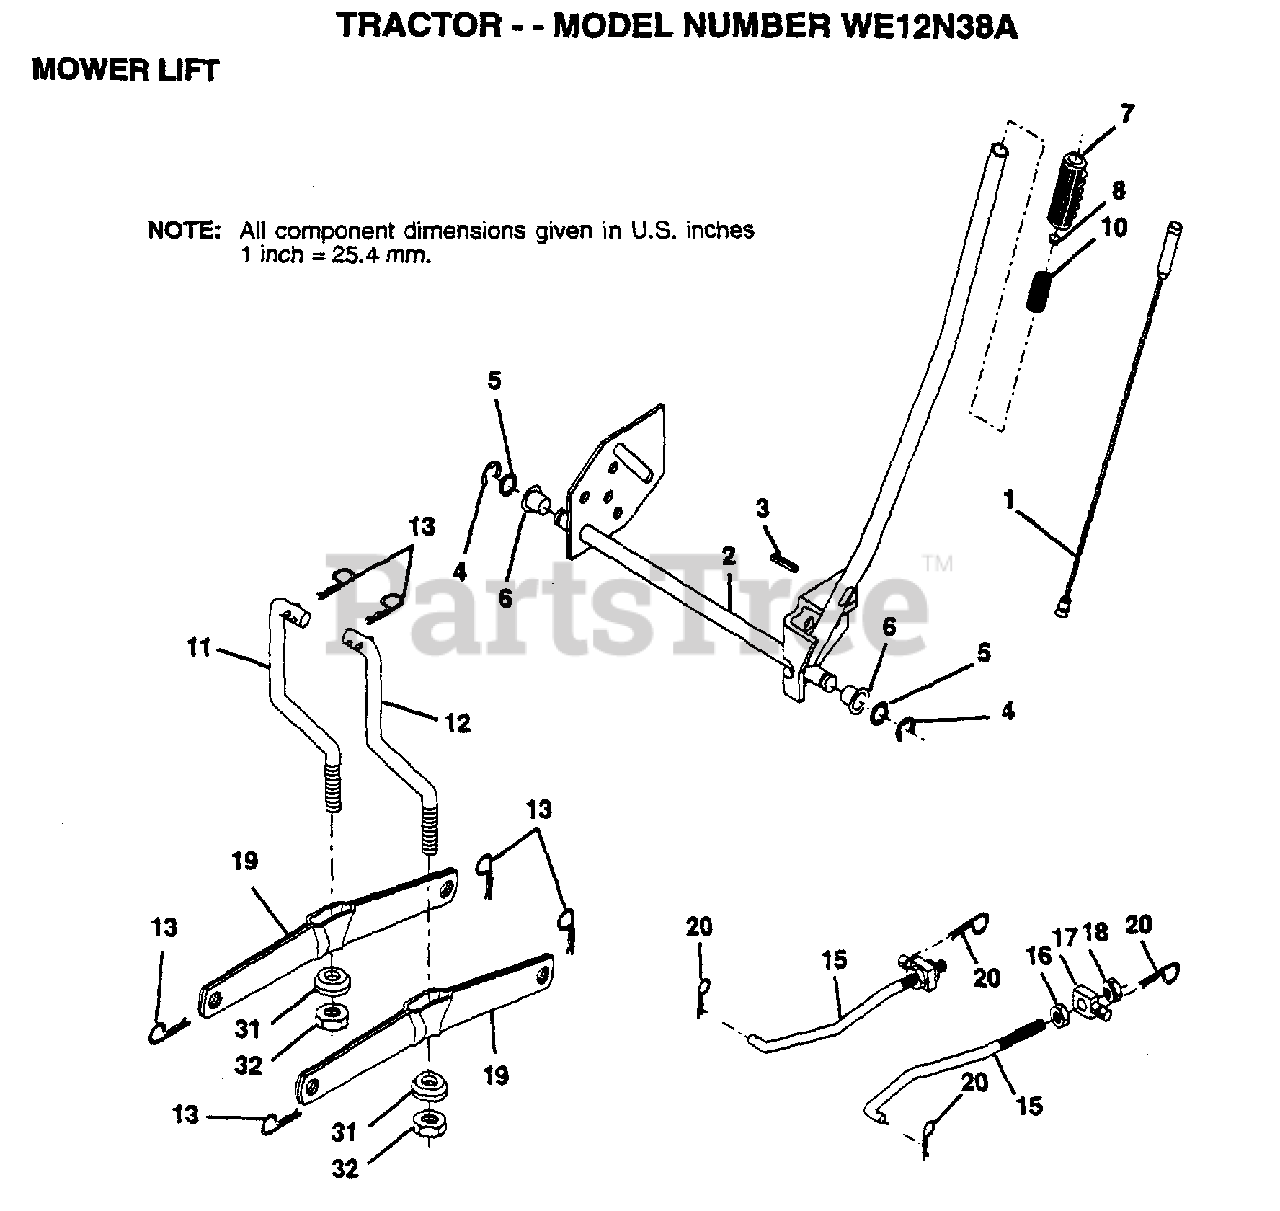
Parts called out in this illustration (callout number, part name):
1	WIRE ASM
3	PIN-GROOVE LT
5	WASHER
6	NYLON BEARING
7	GRIP
15	LINK.FRONT
16	NUT
17	TRUNION
18	NUT.LK.W/WSH.1/2.
19	ARM SUSP REAR
20	RETAINER.SPRING
31	BEARING PVT LH
32	NUT.CROWNLOCK.3/8
